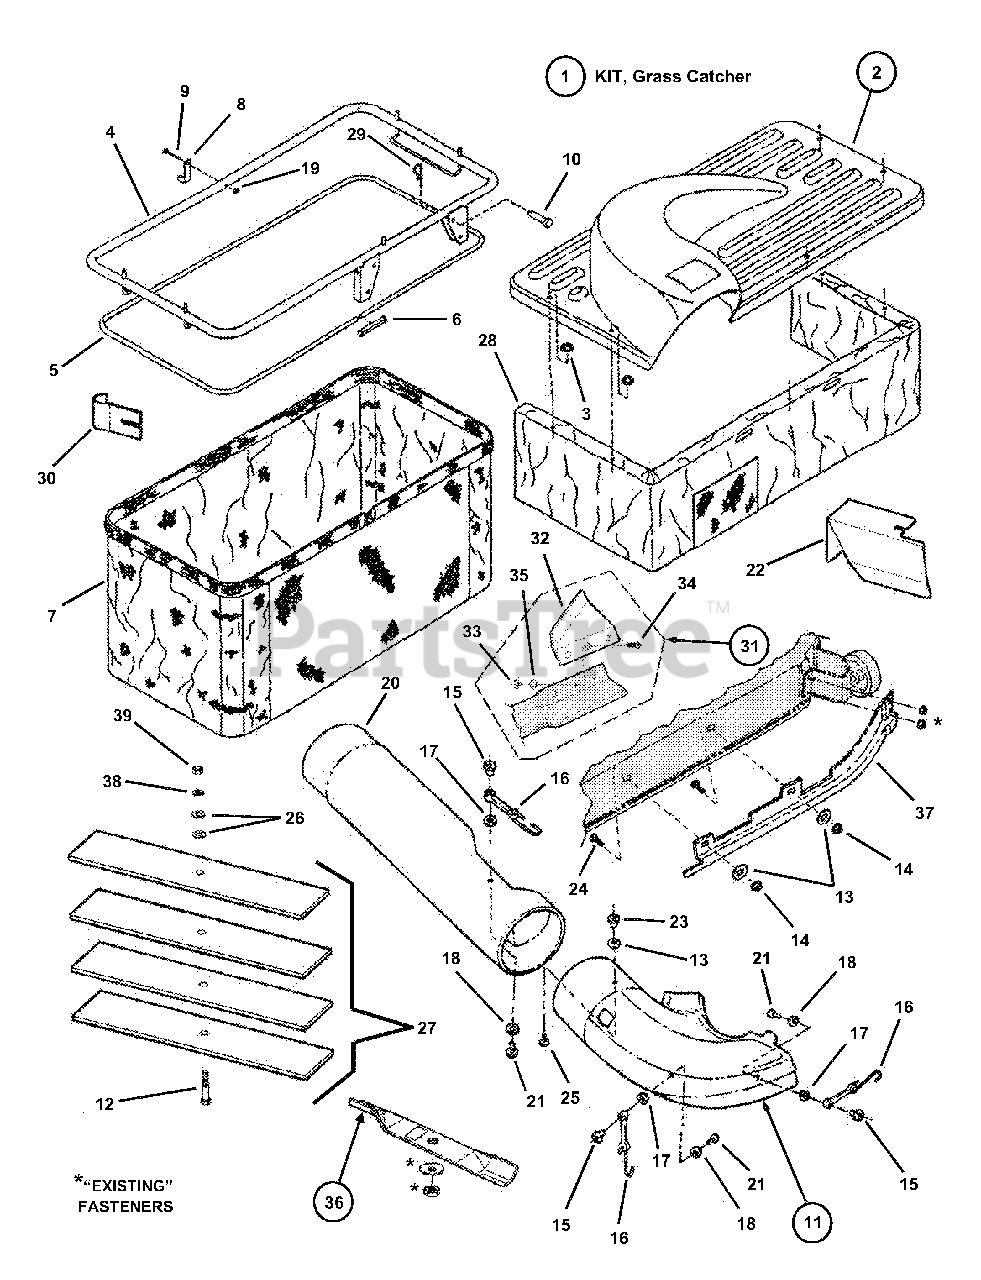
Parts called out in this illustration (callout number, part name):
1	KIT, Grass Catcher (38" Models)
2	TOP, Container
3	WASHER, 5/16" Faceted
4	FRAME, Weldment
5	ROD, Bag
6	CONNECTOR, Bag Rod
7	BAG, Grass
8	LATCH, Top
9	SCREW, #10-32 x 1-3/8" Hex Head Machine
10	PIN, 5/16 x 1-11/16" Clevis
11	ADAPTER, Deck
12	SCREW, 3/8-16 x 2" Hex Head Cap, Grade 5
13	WASHER, 11/32" Flat
14	NUT, 5/16-18 Hex Center Lock
15	NUT, #10-24 x 5/8" Weld
16	STRAP, Mounting Bag Adapter/Tube
17	WASHER, 3/16" Flat
18	WASHER, 7/32" Flat
19	NUT, #10-32 Hex Nyloc
20	TUBE, Grass (37" long)
21	SCREW, #10-24 x 5/8" Pan Head
22	HEAT SHIELD, 14.5 HP
23	TEENUT, 5/16-18
24	SCREW, 5/16-18 x 3/4" Hex Head Cap, Grade 5
25	SCREW, 5/16-18 x 5/8" Cross Recess Pan Head
26	WASHER, 3/8" Flat
27	BALLAST
28	DUST SKIRT
29	PIN, 3/32 x 1-1/2" Hair
30	REINFORCEMENT, Bumper
31	KIT, Air Lift
32	AIR LIFT
33	NUT, 5/16-24 Hex
34	SCREW, 5/16-24 x 11/16" Oval Head Machine
35	WASHER, 5/16" Internal Tooth Lock
36	ASS'Y, High Lift Blade & Decal
37	BAFFLE, 38" Deck MY97
38	WASHER, 3/8" Split Lock
39	NUT, 3/8-16 Hex
